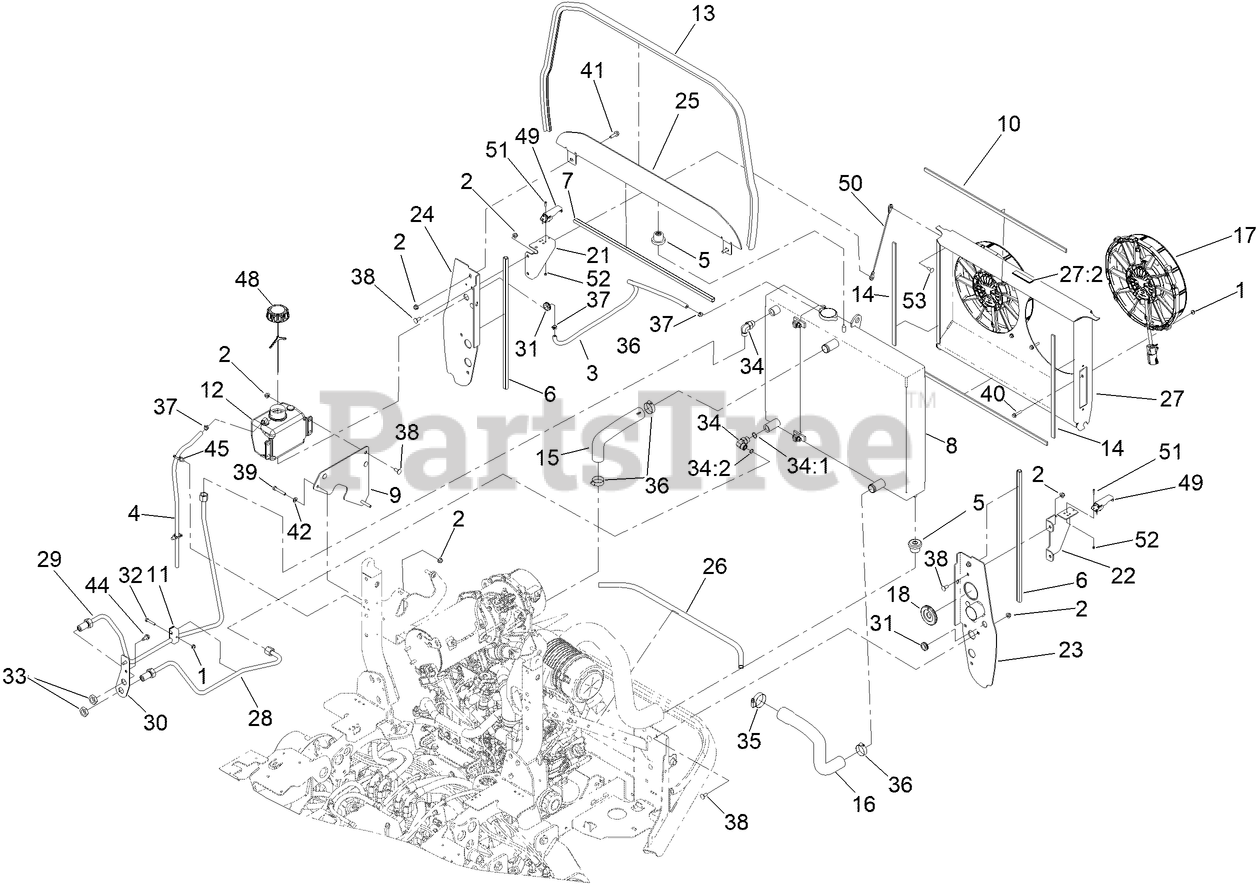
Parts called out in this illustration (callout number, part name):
1	NUT-HF
2	NUT-HF, NI
3	HOSE-FUEL
4	HOSE-FUEL
5	MOUNT-ISOLATOR
6	SEAL-BULB
7	SEAL-BULB
8	COOLING ASM
9	BRACKET-BOTTLE
10	FOAM-ADHESIVE BACKED
11	CLAMP-TWIN
12	TANK-OVERFLOW, W/CAP
13	SEAL-BULB
14	FOAM-ADHESIVE BACKED
15	HOSE-RADIATOR, UPPER
16	HOSE-RADIATOR, LOWER
17	FAN-12", 12V, ELECTRIC, REVERSING
18	GROMMET-SPLIT, 2.38 GD X 0.14 GW X 0.82
21	PLATE-RIGHT LATCH BRACKET
22	PLATE-LEFT LATCH BRACKET
23	SUPPORT-RADIATOR, LH [BLACK]
24	BRACKET-COOLING, RH
25	BRACKET-COOLING, TOP
26	SEAL-BULB
27	FAN SHROUD
27:2	DECAL-WARNING
28	HYDRAULIC TUBE ASM
29	HYDRAULIC TUBE ASM
30	BRACKET-BULKHEAD
31	GROMMET
32	SCREW-HH
33	NUT-BULKHEAD
34	FITTING-ELBOW, 90 DEG
34:1	O-RING
34:2	O-RING
35	CLAMP-HOSE
36	CLAMP-HOSE
37	CLAMP-HOSE
38	SCREW-CARR
39	SCREW-HH
40	SCREW-HHF
41	SCREW-HHF
42	WASHER-PLAIN
44	SCREW-HWHTF
45	CLIP-TIE
48	CAP-W/TETHER
49	LATCH-DRAW
50	CABLE-STOP, SEAT
51	SCREW-BUTTON
52	NUT-LOCKROHS
53	BOLT-CARR
